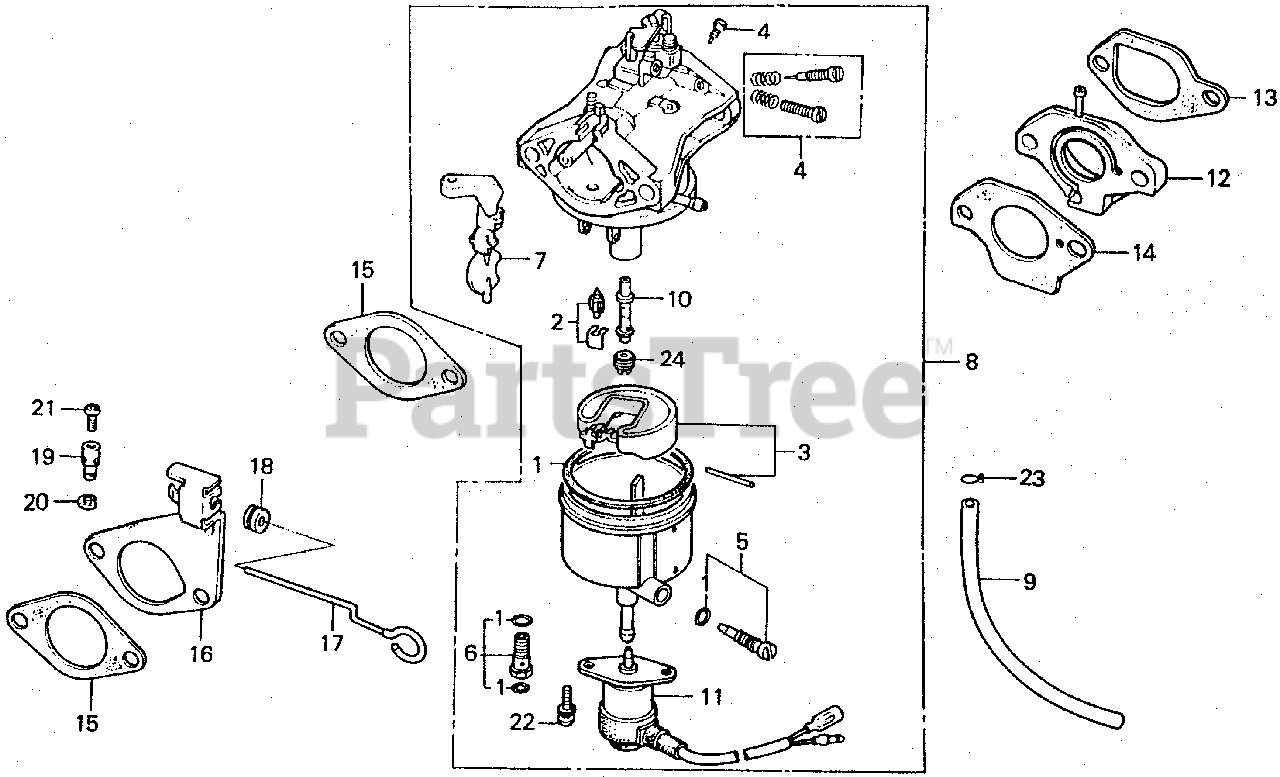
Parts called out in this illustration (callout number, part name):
1	GASKET SET
2	VALVE SET, FLOAT
4	SCREW SET A
5	SCREW SET, DRAIN
6	SCREW SET
6	SCREW SET B (NOT AVAILABLE)
6	SCREW SET B
8	CARBURETOR ASSY. (BB36A A) (NOT AVAILABLE)
8	CARBURETOR ASSY. (BB36A B) (NOT AVAILABLE)
8	CARBURETOR ASSY.
9	TUBE, DRAIN
10	NOZZLE, MAIN (NOT AVAILABLE)
10	NOZZLE, MAIN
11	VALVE ASSY., SOLENOID (NOT AVAILABLE)
11	VALVE ASSY., SOLENOID
12	INSULATOR, CARBURETOR (NOT AVAILABLE)
13	GASKET, INSULATOR
14	GASKET, CARBURETOR
15	GASKET, AIR CLEANER
16	STAY, CHOKE CONTROL
17	ROD, CHOKE CONTROL (NOT AVAILABLE)
18	GROMMET, CHOKE ROD
19	HOLDER, CABLE
20	CIRCLIP (5MM)
21	SCREW, PAN (4X8)
22	SCREW-WASHER (5X12)
23	CLIP, TUBE (C9)
24	JET, MAIN (#92)
24	JET, MAIN (#92) Use from Engine SN BB36B A.
24	JET, MAIN (#98)
24	JET, MAIN (#100)
24	JET, MAIN (#102)
24	JET, MAIN (#80)
24	JET, MAIN (#82)
24	JET, MAIN (#85)
24	JET, MAIN (#88)
24	JET, MAIN (#90)
